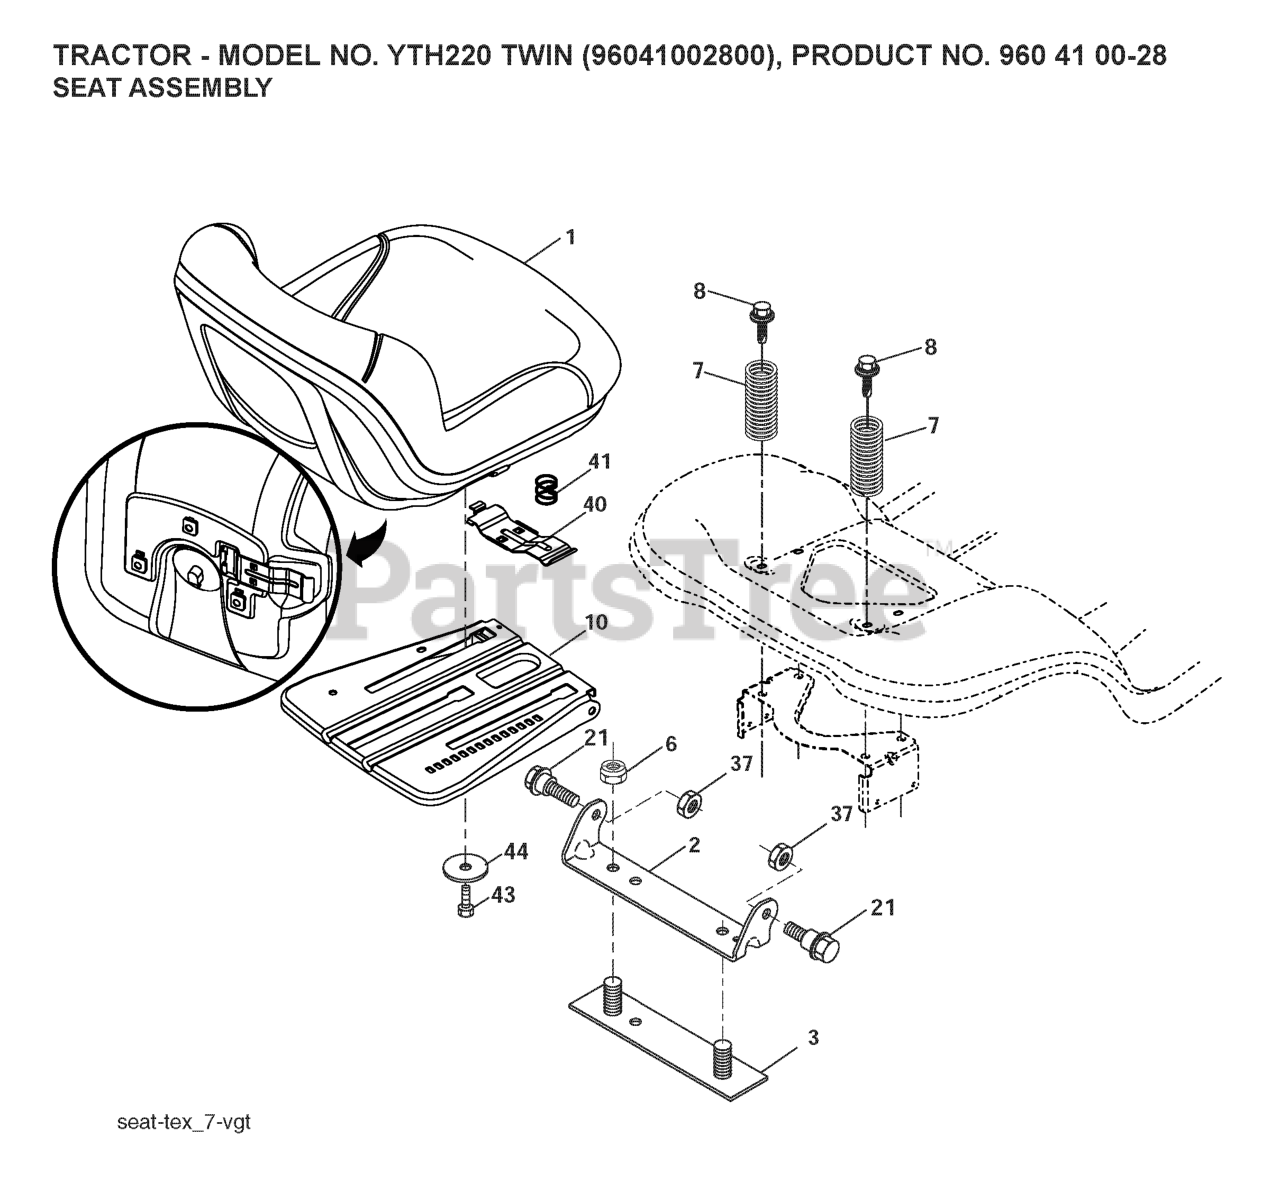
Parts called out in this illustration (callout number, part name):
1	SEAT - GREY
2	BRKT.PIVOT.FENDER
3	STRAP
6	NUT
7	SPRING COMPRESSION
8	BOLT.5/16-18UNCX3/4 W/SEMS.BLK
10	PAN.ASM.SEAT.3PT
21	BOLT.SHOULDER.5/16-18
37	NUT.71038.31-18.HEX.NYLOCK
40	HANDLE.SLIDE.SEAT.TEX.BLACK
41	SPRING.LATCH.SEAT.TEX
44	WASHER 13/32 X 2-3/8 X 12GA
